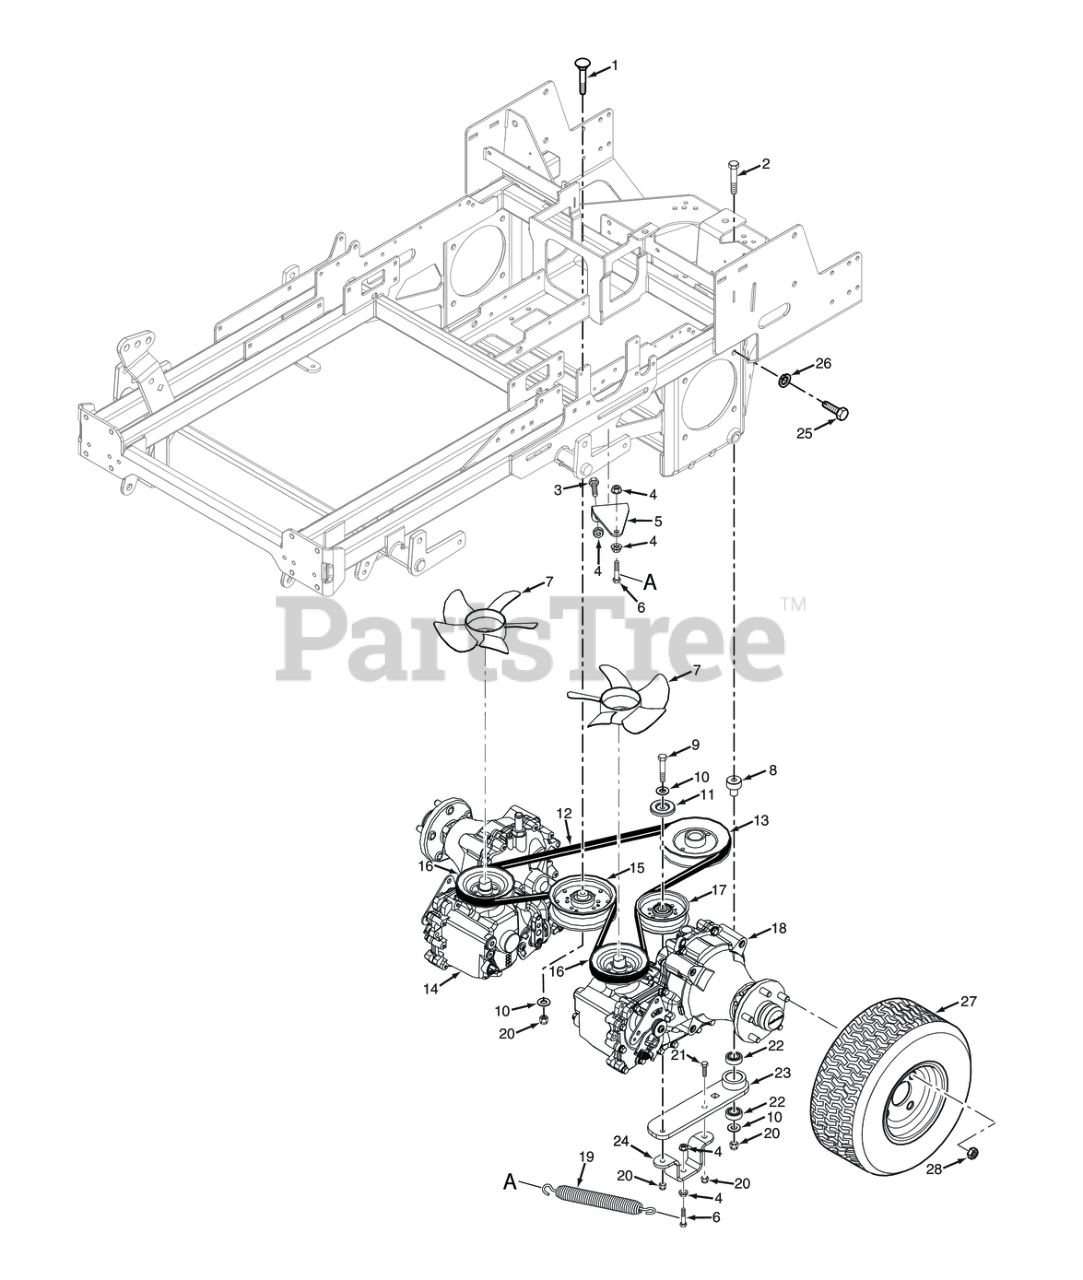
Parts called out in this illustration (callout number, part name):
1	Carriage Bolt, 3/8-16 x 2-1/2"
2	Bolt, Hex Head 3/8-16 x 3" - 52"
3	Bolt, Hex Head, 3/8-16 x 1 Gr. 5
4	NUT, 3/8-16 SERRATED FLANGE HEX HEAD
5	Mounting Bracket, Spring - Idler Arm
6	Bolt, Hex Head 3/8-16 x 1-1/2" Grade 8 Black
7	Kit, Fan / Pulley
8	Pivot, Idler Long - 52"
9	Capscrew, Hex Head 3/8-16 x 2.75"
10	Flatwasher, 3/8 (.391 x .938 x .105 HD) Grade 8
11	Quick Pin, 5/16" Dia.
12	Belt, Pump Drive STT
13	Pulley, 5.80" Dia. - 1.125 Bore
14	Transaxle, RH
15	Idler Pulley, Belt Clutch
16	Kit, Fan / Pulley
17	Pulley, 4" Dia. Idler
18	Transaxle, LH
19	Spring, Pump Drive
20	HEX NUT, ELASTIC STOP LOCK, 3/8-16
21	Bolt, Hex Head 3/8-16 x 1-1/4", Kawasaki FX / FS
22	BEARINGS, BALL, NEUTRAL RETURN
23	Idler Arm Assembly
24	Mounting Bracket, Idler
25	Bolt, Hex Head 1/2-13 x 1-1/4"
26	Lockwasher, 1/2" Spring
27	Wheel Assembly, 24 x 12-12 4-Ply (5-Hole)
28	Wheel Nut, 1/2-20 x 13/16
